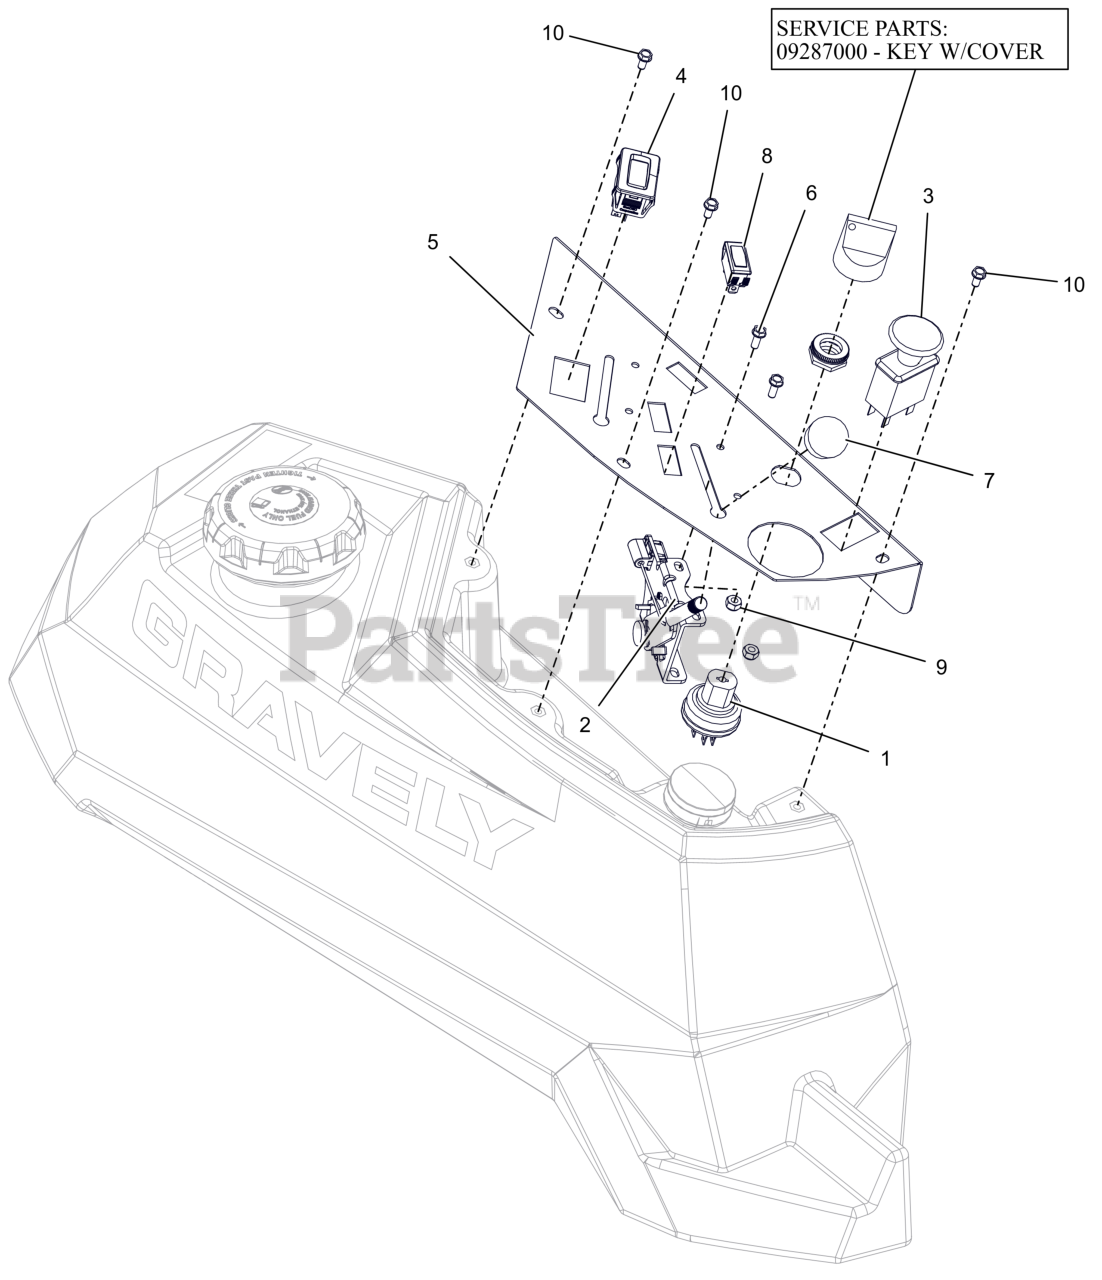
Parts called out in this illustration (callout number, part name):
1	SWITCH, IGNITION
1	KEY, W/ SHIELD
2	CABLE, PRO-CTRL 35.50"
3	SWITCH, CLUTCH
4	HOUR METER
5	PT100 CONTROL PANEL - RED
6	BLT, HWH #10-24X.50 ZCC
7	KNOB-CONTROL-BLACK .38-16X.50
8	LIGHT, INDICATOR (RED)
9	NUT-LK-NYL #10-24 G2 ZCC
10	SCR-MCH 10-24X.38 HWHSTAINLESS
